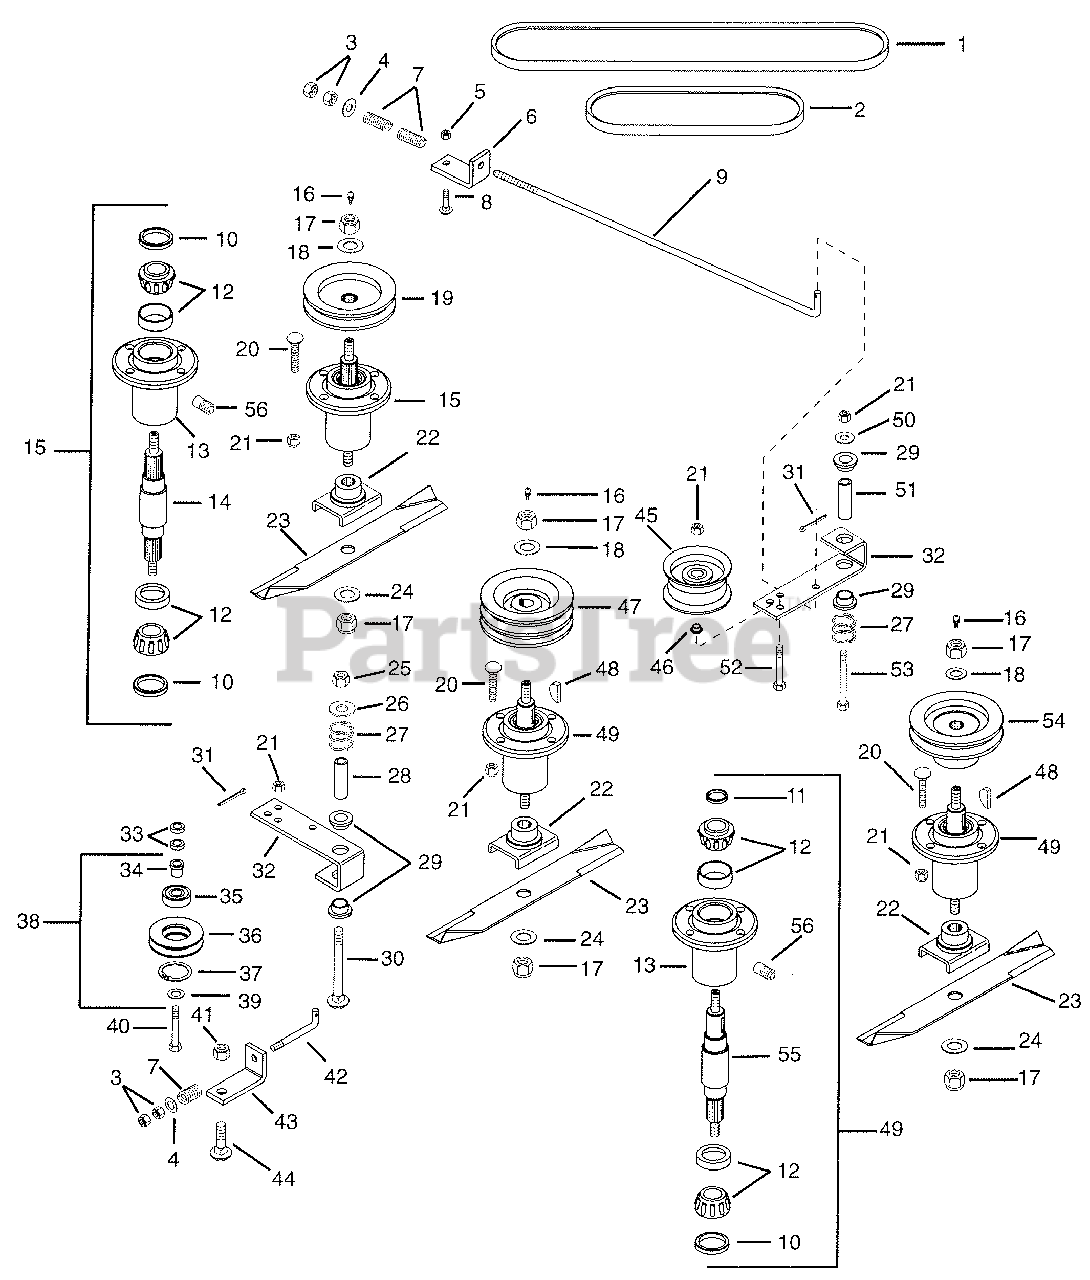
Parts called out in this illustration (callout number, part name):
1	Drive Belt 54.90 X 17/32
2	Right Spindle Belt 18.05 X .495
3	Nut Hex .375-16 Grade 2
4	Washer Flat Steel .406 X .812 X .065
5	Nut Locking Nylon .312-18 Grade 2
6	Bracket, Belt Tensioner
7	Spring Compression .125 X .78 X 1.000
8	Bolt, Round Head Square Neck .31-18 X 1.0
9	Rod, Idler LH
10	Seal 1.987 X 1.375 X .313
11	Seal 1.987 X 1.500 X .313
12	Assembly, Bearing Cup & Cone
13	Bearing Housing
14	Shaft. Spindle
15	Service Kit Spindle Assembly
16	Fitting, Lube 1/8
17	Nut Locking Nylon .625 -11 Grade 2
18	Washer Flat Steel .687 X 1.312 X .135
19	Sheave
20	Bolt Round Head Square Neck .38-16 X 1.375
21	Nut Locking Nylon .375-16 Grade 2
22	Weldment Blade Cradle
23	Blade, 50 Inch Mower
24	Washer Flat Nylon .656 X 1.312 X .095
25	Nut Lockin .50-13
26	Washer Flat Steel .531 X 1.250 X .100
27	Spring Compression .085 X 1.00
28	Bushing Steel .560 X .750 X 2.44
29	Bushing Flange .762 X 1.0 X .580 X 1.48
30	Bolt Round Head Square Neck .50-16 X 3.50
31	Pin Cotter .09 X .75
32	Arm, Idler Pivot
33	Bushing .406 X .750 X .188
34	Bushing Flange .786 X 1.0 X .79
35	Bearing Ball 1.85 X .787 X .55
36	Sheave Idler
37	Ring Retaining Internal 2.05 X .062
38	Assembly Idler Sheave
39	Washer Flat Steel .375 X 1.125 X .065
40	Bolt Hex .38-16 X 2.00 Grade 5
41	Nut Locking Nylon .50-13 Grade 2
42	Rod Idler
43	Bracket Belt Tensioner
44	Bolt Round Head Square Neck .500-13 X 1.50
45	Idler Flat 4 - .687 X .38
46	Bushing Flange .406 X .88 X .270 X .140
47	Sheave
48	Key, Woodruff .25 X 1
49	Service Kit Spindle Assembly
50	Washer Flat Steel .438 X 1.0 X .083
51	Bushing, Steel .437 X .750 X 2.44
52	Bolt Hex .38-16 X 2.25 Grade 5
53	Bolt Hex .38-16 X 3.25 Grade 5
54	Sheave
55	Shaft. Spindle
56	Relief Fitting
